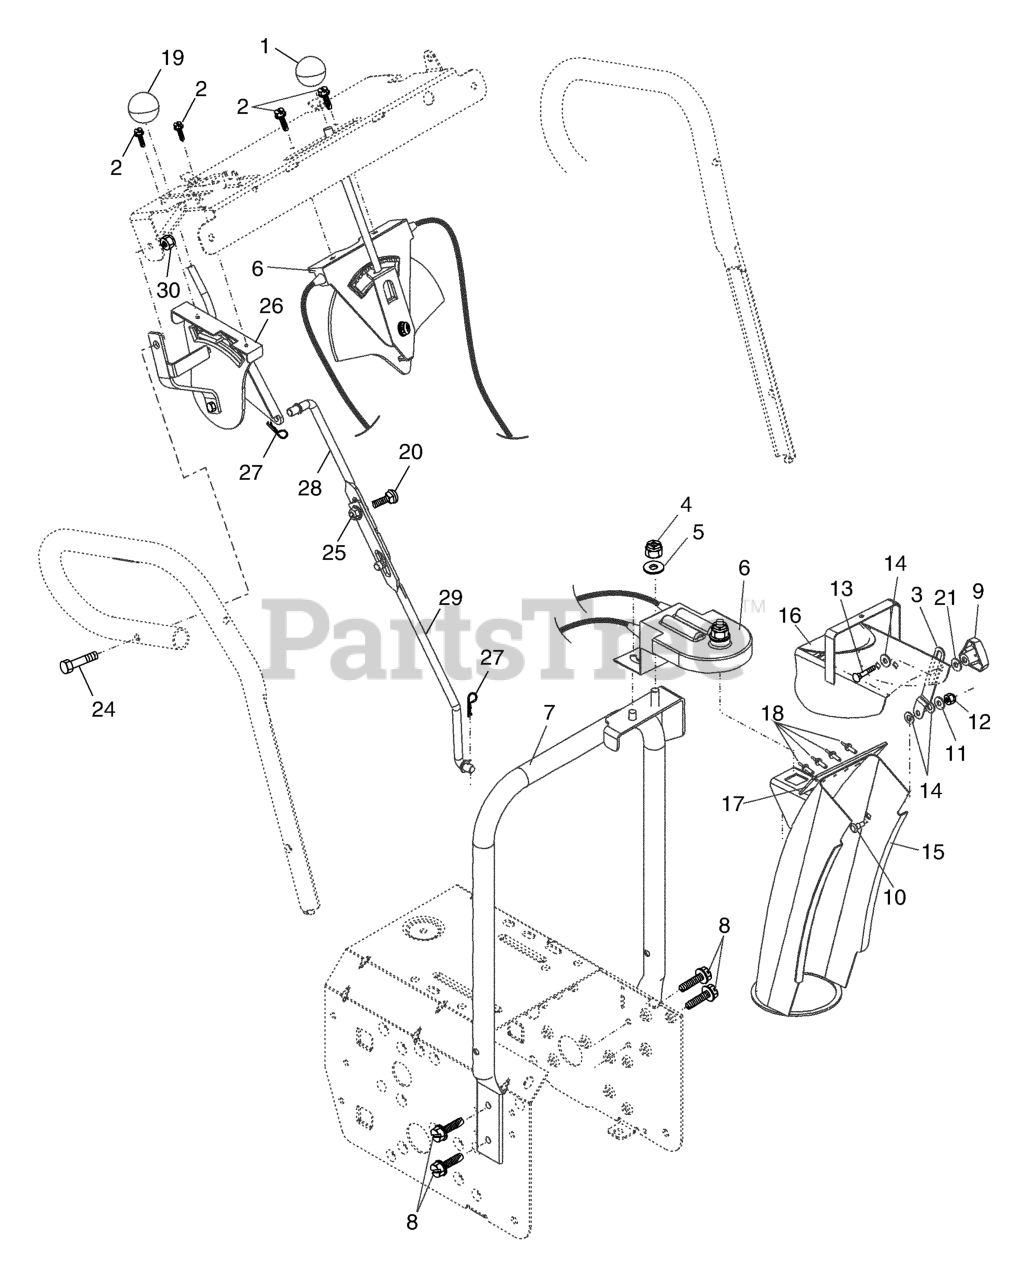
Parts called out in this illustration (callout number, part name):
1	KNOB, LEVER
2	SCREW #10-24 X 5/8
3	STRAP, CHUTE
4	NUT
5	WASHER
6	CONTROL ASSY, CHUTE ROTATER
7	SUPPORT CHUTE ROTATER
8	SELF-TAPPING SCREW 5/16-18X3/4
9	KNOB.SKID.PLATE
10	SHOULDER BOLT
11	WASHER
12	LOCKNUT.NYLOC.1/4-20
13	BOLT
14	WASHER, NYLON FRICTION
15	CHUTE ASSY
16	DEFLECTOR.WELDMENT.PNT.ORANGE
17	SEAL, DEFLECTOR
18	RIVET BLIND
19	RP KNOB, SPEED CONTROL LEVER
20	BOLT
21	WASHER.20X8.5
25	NUT.FLANGE.5/16
26	LEVER ASSEMBLY, SPEED CONTROL
27	SPRING RETAINER
28	ROD, UPPER SPEED CONTROL
29	ROD, LOWER SPEED CONTROL
30	NUT.71038.31-18.HEX.NYLOCK
